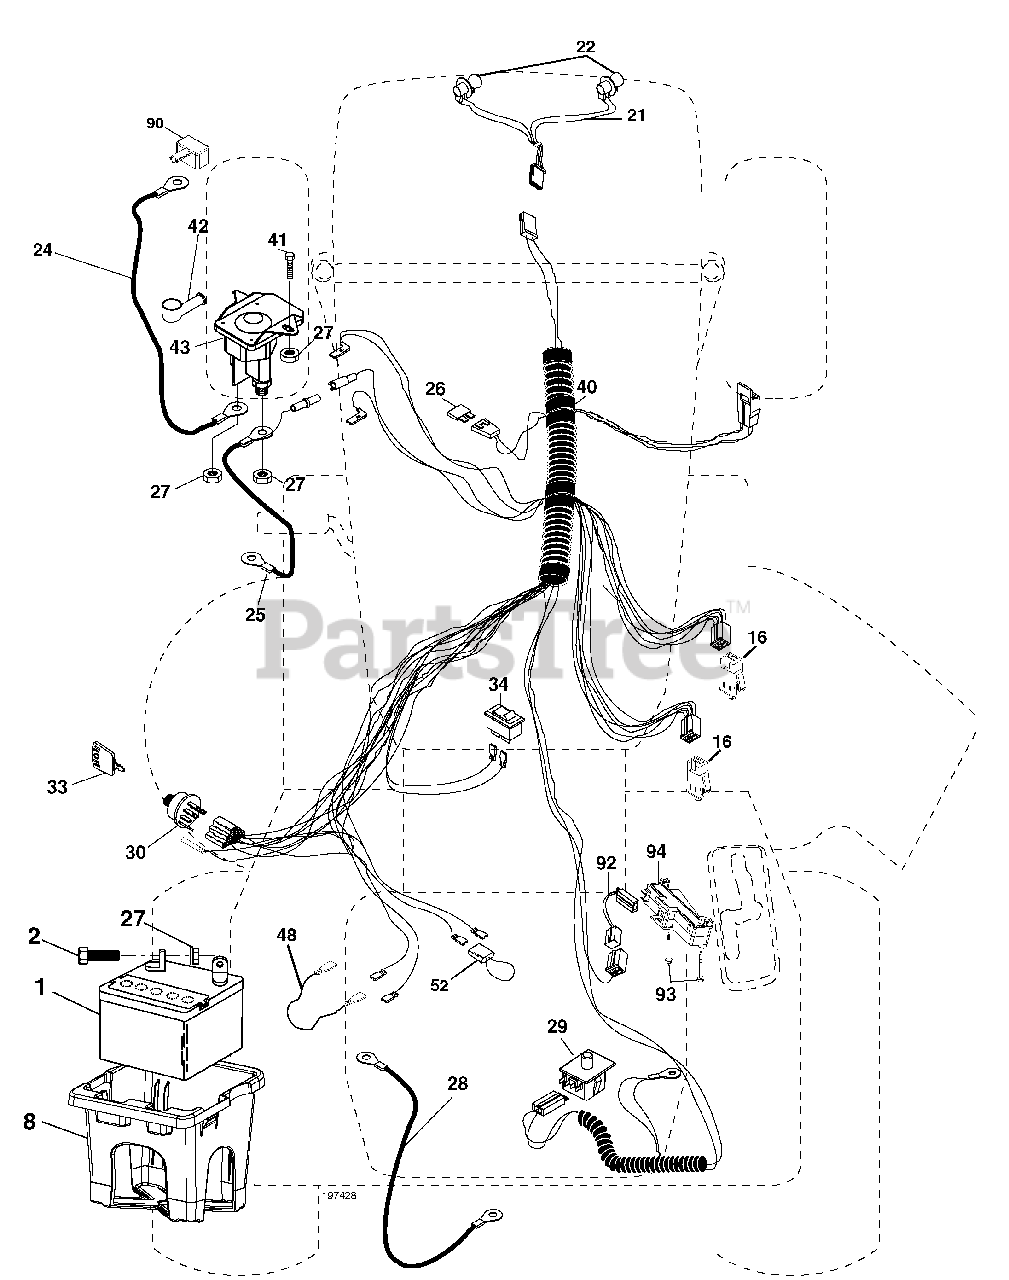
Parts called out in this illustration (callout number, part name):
1	Battery
2	Bolt Hex Hd 1/4-20 unc x 3/4
8	Box Battery
16	Switch Interlock
21	Harness Asm Light W/4152j
22	Bulb Light #1156
24	Cable Battery 6 Ga. 11"red
25	Cable Battery
26	Fuse 20 AMP
27	Nut Keps Hex 1/4-20 unc
28	Cable Ground 6 Ga. 12"black
29	Switch
30	Switch Ign
33	Key Ign
34	Switch Light/Reset
40	Harness Ign
41	Bolt Blk Fin Hex 1/4-20
42	Cover Terminal Red
43	Solenoid
48	Adapter Ammeter
52	Protection Wire Loop
90	Cover Terminal Battery
92	Harness Pigtail
93	Screw Plastite 10-14 x 2.0
94	Module Reverse
